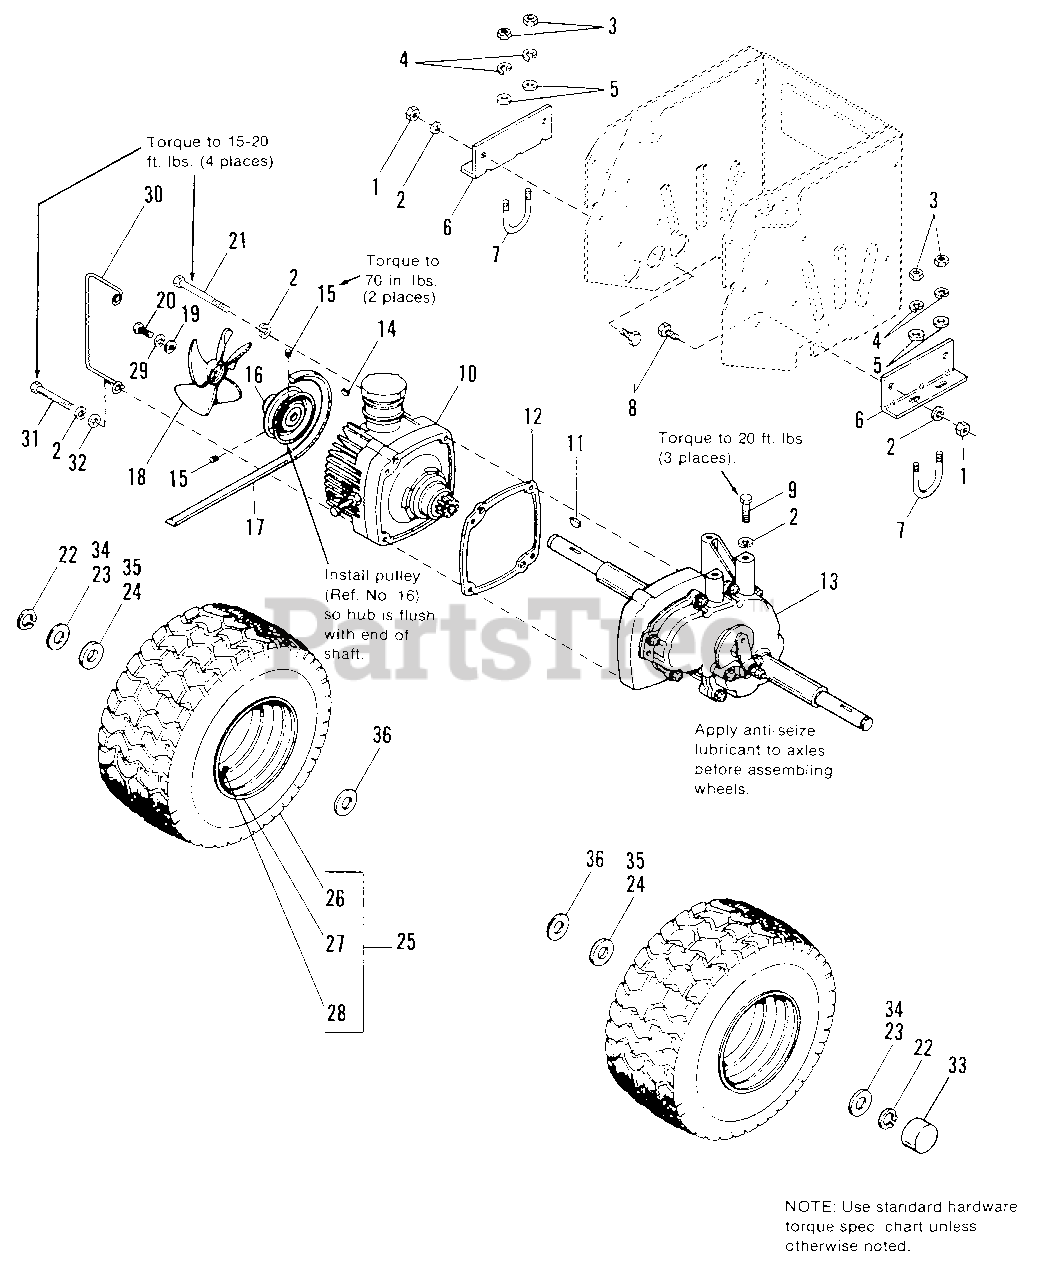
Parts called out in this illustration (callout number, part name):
1	NUT, Hex, 3/8-16
2	LOCKWASHER, 3/8
3	NUT, Hex, 5/16-18
4	LOCKWASHER, 5/16
5	WASHER, 5/16
6	SUPPORT, Transmission
7	"U" BOLT, Axle
8	CAPSCREW, Hex, 3/8-16 x 3/4
9	CAPSCREW, Hex, 3/8-16 x 1
10	TRANSMISSION, Hydrostatic (See page 18 & 19)
11	KEY, Woodruff, #18, 1/4 x 1-1/4
13	GEAR REDUCTION & DIFFERENTIAL ASSY. (See page 46 for parts list)
14	KEY, Woodruff, #3, 1/8 x 1/2
15	SETSCREW, Sq. Hd., 1/4-28 x 1/2
16	PULLEY, Transmission
17	BELT, "V" Drive
18	FAN, 7" Diameter
19	WASHER, 1/4 x 1-1/4 x 14 Ga.
20	CAPSCREW, Hex, 1/4-2 x 1/2
21	CAPSCREW, Hex, 3/8-16 x 3
22	RING, Retainer
23	WASHER (1690759 only)
24	WASHER, Plain, 1 x 1-3/4 x 1/4 (Mfg. No. 1690759 only)
25	WHEEL & TIRE ASSY. 18 x 9.50-8 (Mfg. No. 1690759 only)
25	WHEEL & TIRE ASSY., 18 x 8.50-8 (Mfg. Nos. 1690846 & 1690912 only)
26	TIRE (Carlisle) 18 x 9.50-8 (Mfg. No. 1690759 only)
26	TIRE, 18 x 8.50-8 (Carlisle)(Mfg. Nos. 1690846 & 1690912 only)
27	WHEEL ASSY. (Mfg. No. 1690759 only)
27	WHEEL ASSY. (Mfg. Nos. 1690846 & 1690912
28	VALVE STEM & CAP
29	LOCKWASHER, 1/4
30	STOP, Drive Belt
31	CAPSCREW, Hex, 3/8-16 x 3-1/4, Gr. 5
32	WASHER, 3/8 Std.
33	CAP, Hub, Threaded (Mfg. Nos. 1690846 & 1690912 only)
34	WASHER (Mfg. Nos. 1690846 & 1690912 Only)
35	WASHER, Plain, 1-1/32 x 1-3/4 x 3/16 (Mfg. Nos. 1690846 & 1690912 only)
